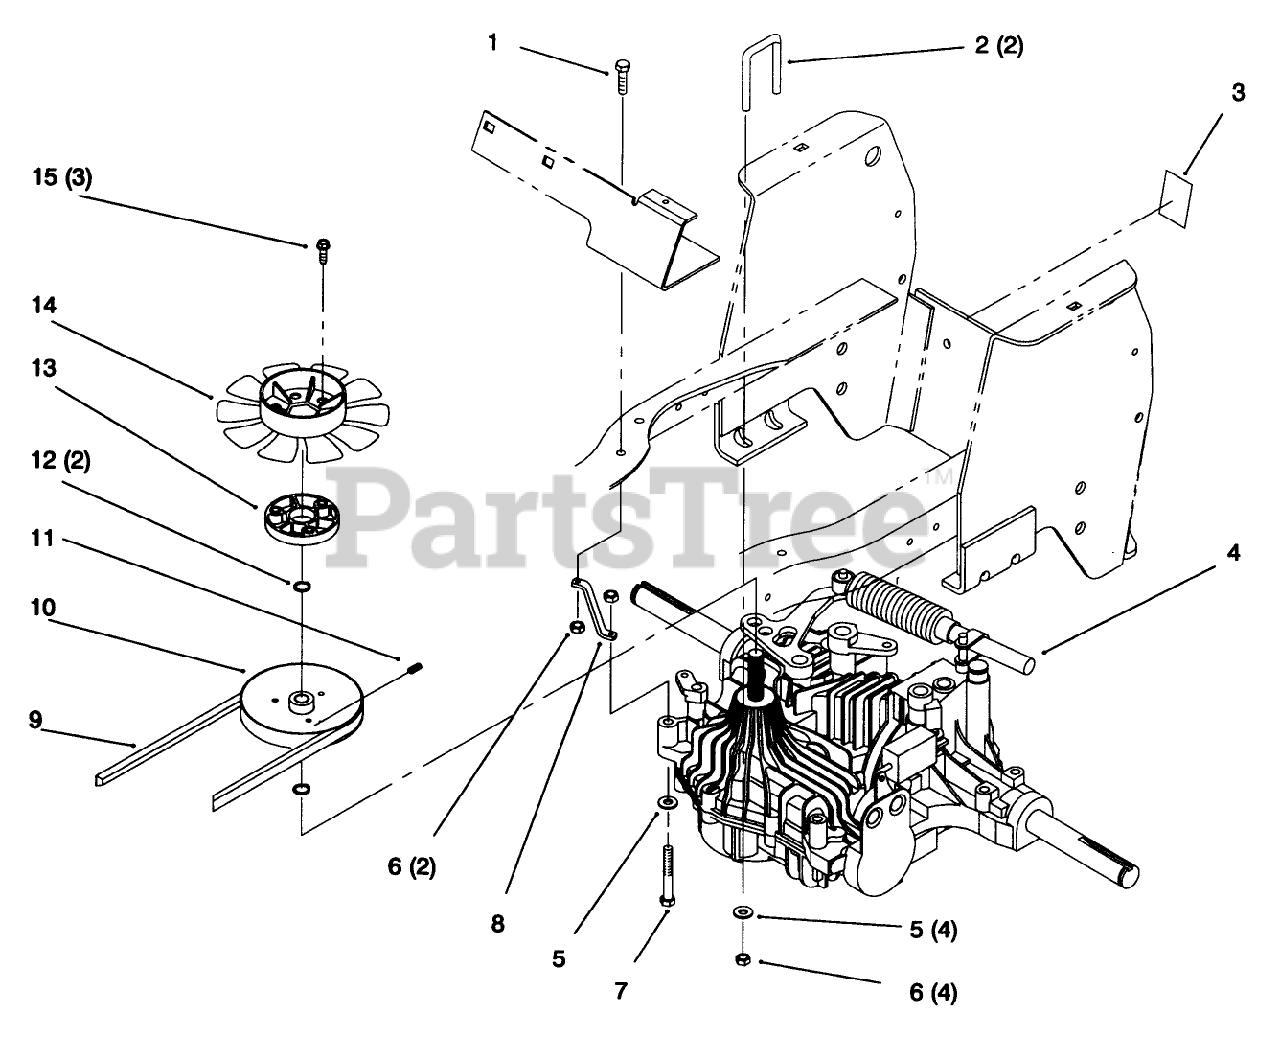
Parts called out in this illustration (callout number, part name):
1	SCREW-HH
2	U-BOLT
3	DECAL-VALVE, HYDRO
3	DECAL-BYPASS VALVE
5	WASHER-PLAIN
6	NUT-LOCK, NI
7	SCREW-HH
8	STRAP-TRQ HY
10	PULLEY-HYDRO TRANS
11	SCREW-HSH
12	RING-RETAINING
13	SPACER - FAN
14	FAN - HYDRO
15	SCREW-HWHTF
